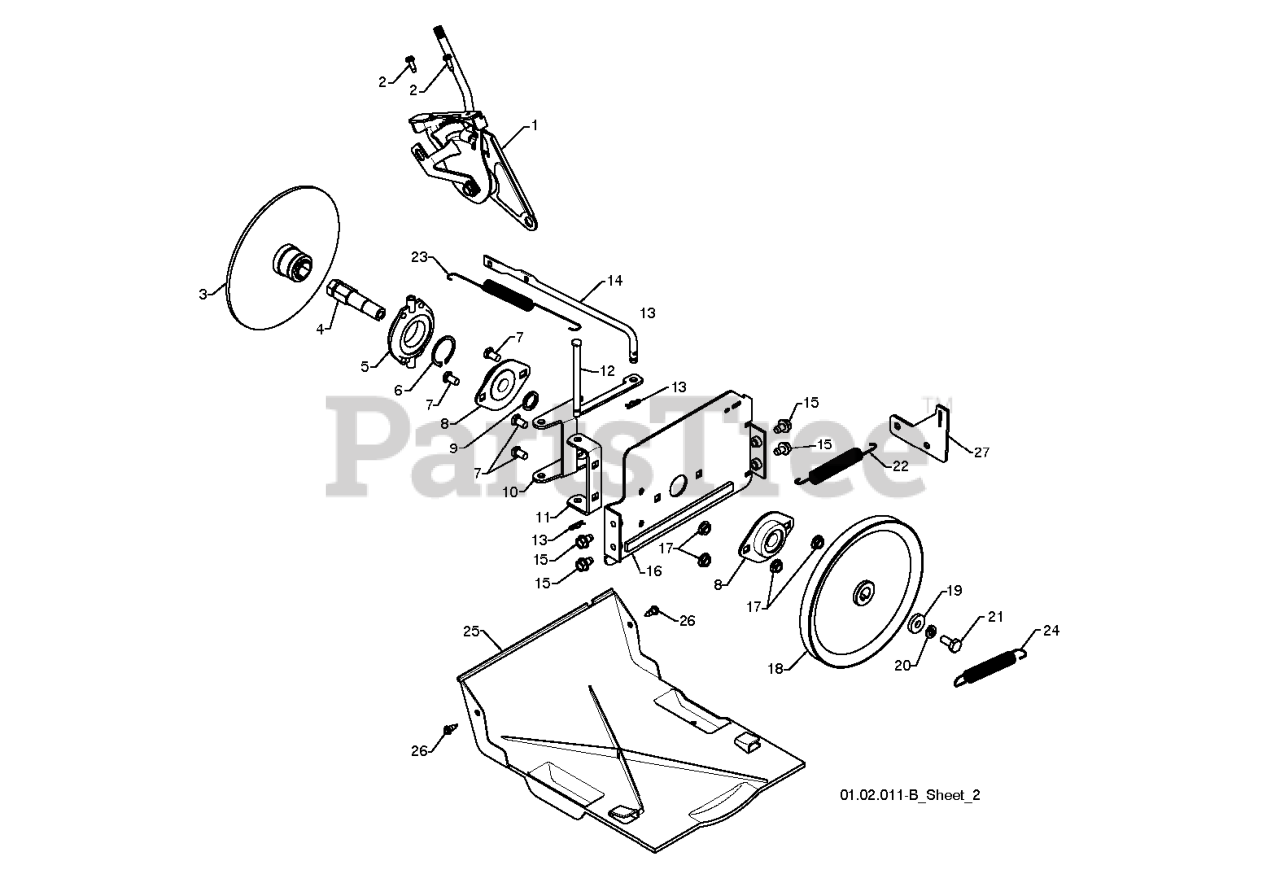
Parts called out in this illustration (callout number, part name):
1	HEAD ASSY SPEED
2	SCREW #10-24 X 5/8
3	DRIVE PLATE WELDMENT
4	SHAFT.HEX.SHORT
5	TRUNNION BEARING ASSY
6	RETAINING RING (2 2)(3 2)
7	BOLT
8	BEARING FLANGE
9	SPACER, BEARING
10	LEVER.SHIFTER.PLATE.BLACK
11	BRACKET, SHIFTER SUPPORT
12	PIN, PIVOT LEVER
13	RETAINER CLIP PM
14	ROD.CLUTCH.YELLOW.ZINC(VT)
15	Screw 5/16-18 x 1/2 Hex, Self Tapping 5/16-18 x 1/2
16	PLATE.DRIVE.MOUNTING.BLACK
17	NUT.FLANGE.5/16
18	PULLEY.TRACTION.7.75
19	WASHER, FLAT
20	WASHER.LOCK.HVY.HLCL.SPR.5/16
21	Screw, Hex Head 5/16-18 x 3/4
22	SPRING.TRACTION.IDLER
23	SPRING.RETURN
24	SPRING, BRAKE
25	PAN.BOTTOM.PLASTIC
26	SCREW, HEX HEAD, TAPPING
27	BRACKET.TRACTION.SPRING.
